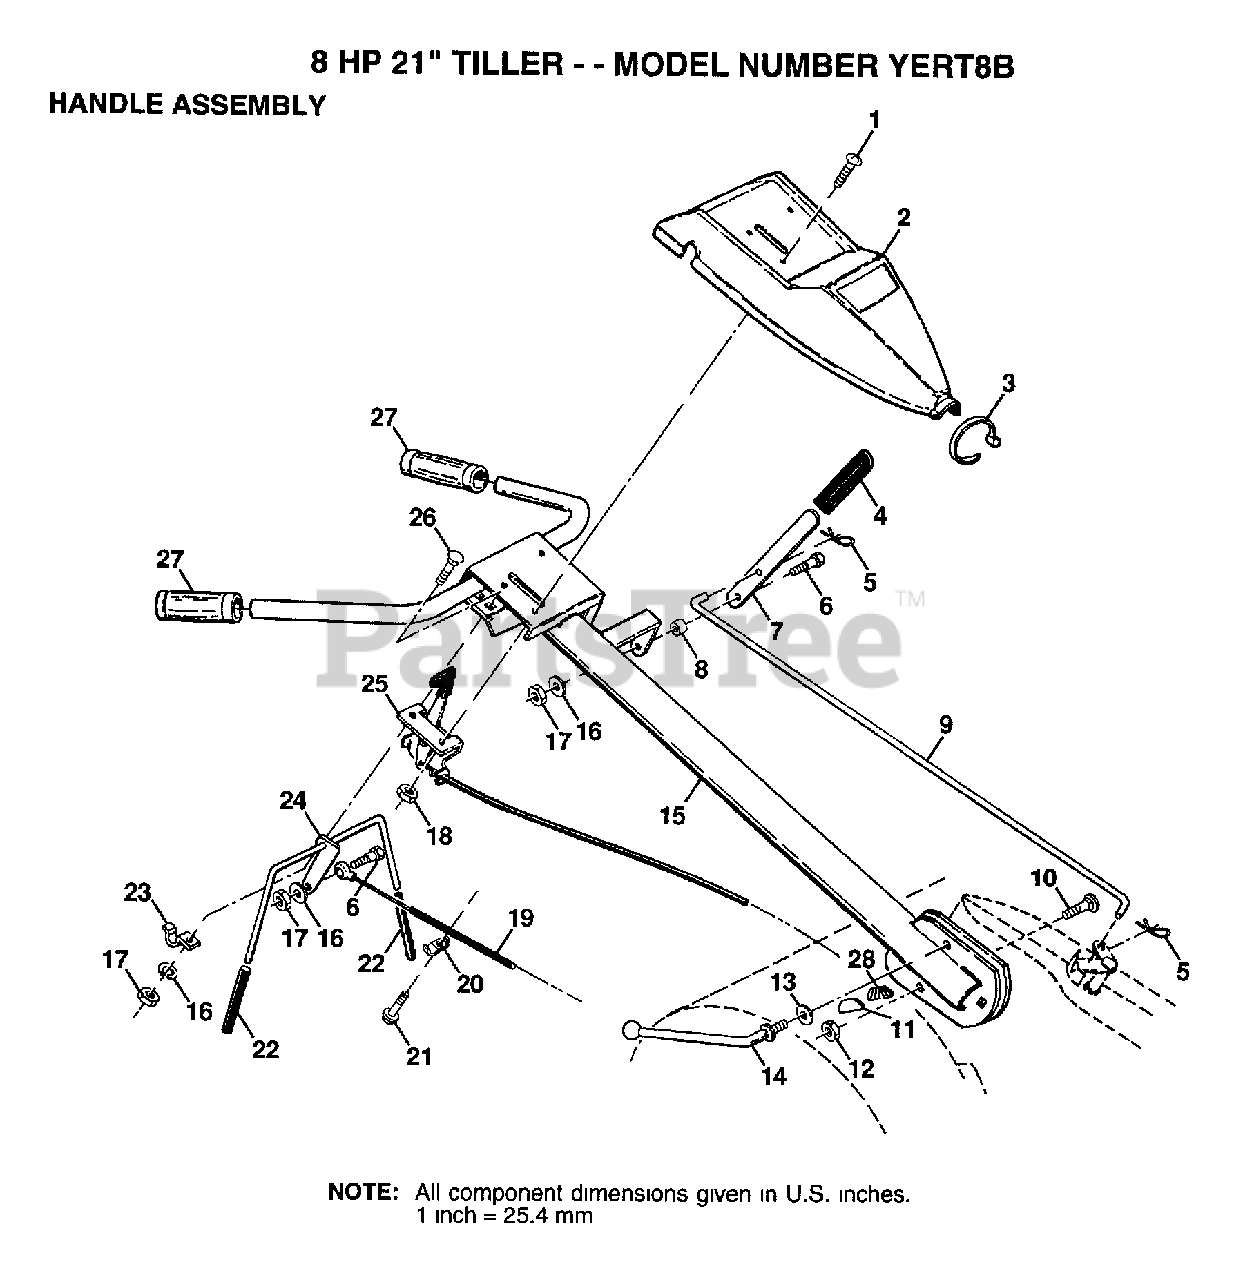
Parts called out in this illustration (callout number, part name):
1	SCREW
2	"PANEL,CONT TI"
3	TIE CABLE CRT
4	GRIP T
5	RETAINER M
6	SHOULDER BOLT ST
7	SHIFT HANDLE CRT
8	GROMMET CRT
9	ROD.SHIFT
11	LOCK CRT
12	LOCKNUT
13	WASHER CRT
14	LEVER LOCK CRT
16	LOCKWASHER
19	CABLE-CLUTCH CRT
20	CONDIUT CLIP T
22	GRIP BAR CRT
24	"ASSY CONTROL, BAR"
25	CONTROL.THROTTLE
26	BOLT
27	GRIP NUB SNGL HDL
28	LOCK.HANDLE
